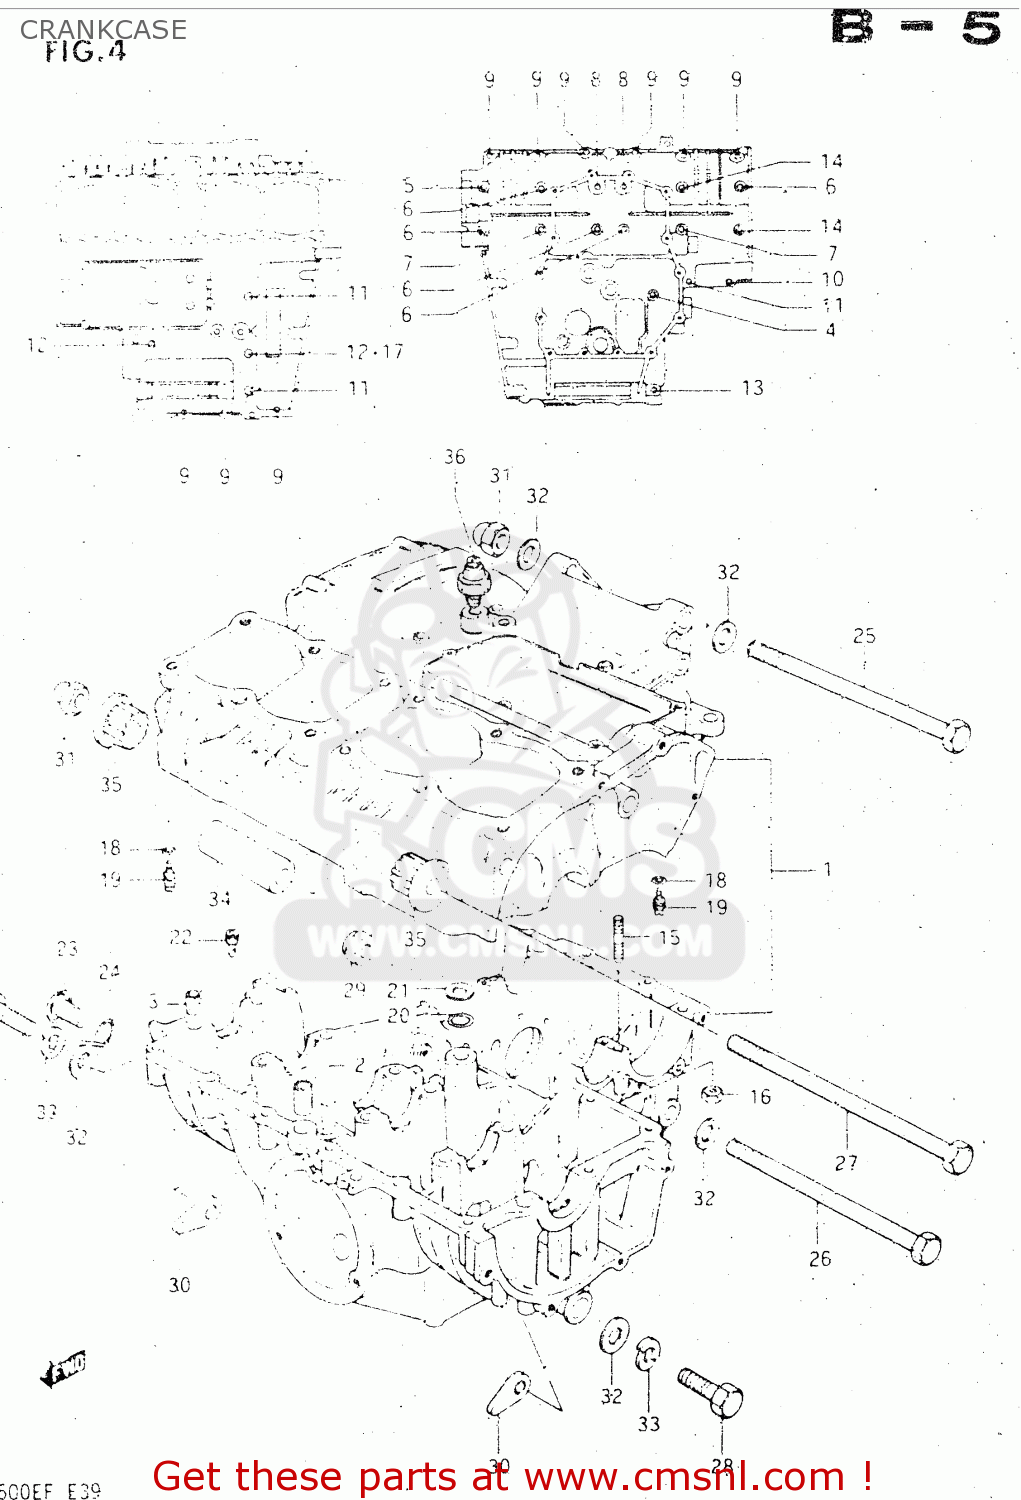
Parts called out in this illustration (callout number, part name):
1	CRANKCASE SET
2	PIN(10.4X13X22)
3	PIN (11X20)(SUS)
4	BOLT(6X100)
5	BOLT
6	BOLT(8X110)
7	BOLT
8	BOLT
9	BOLT
10	BOLT 6X55
11	BOLT
12	BOLT (5X95)
13	BOLT 8X60
14	BOLT (8X90)
15	STUD BOLT
16	NUT 6MM
17	GASKET(6.2X13X1.2) (NAS)
18	O RING(D:1.2,ID:4)
19	JET,OIL GALLERY
20	O RING(D:3.2,ID:12.9)
21	WASHER,THRUST
22	JET,AIR
23	PLUG
24	O RING(D:2.4,ID:16.8)
25	BOLT
26	BOLT
27	BOLT
28	BOLT
29	NUT 10MM
30	NUT
31	NUT
32	WASHER
33	LOCK WASHER
34	SPACER (10.2X16X105.5)
35	BUSH
36	SWITCH ASSEMBLY
